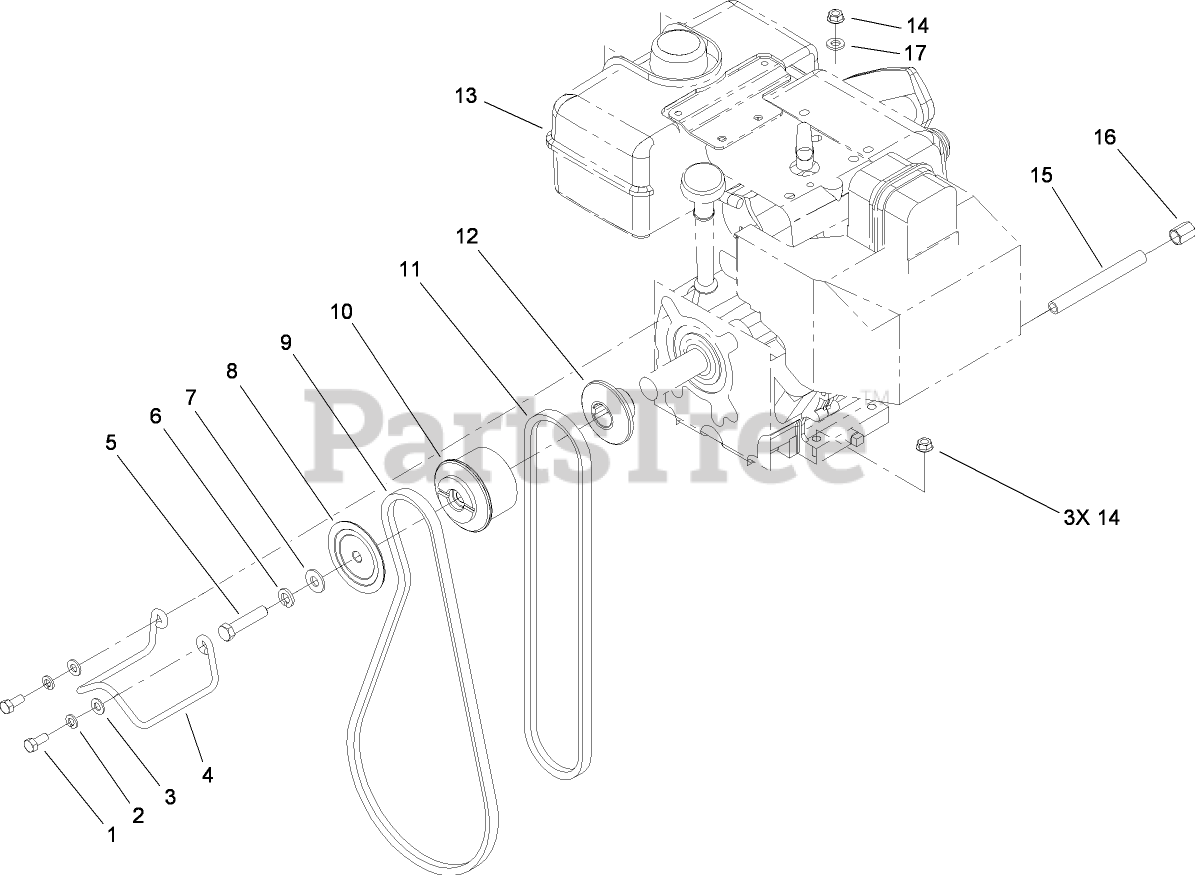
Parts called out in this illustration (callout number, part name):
1	SCREW-HH
2	WASHER-LOCK
3	WASHER-PLAIN
5	SCREW-HH
6	WASHER-LOCK
7	WASHER-FLAT
8	SHEAVE-HALF, IMPELLER
9	BELT-V
10	PULLEY-ENGINE, CENTER
11	V BELT-TRACTION
12	SHEAVE-HALF, TRACTION
13	Loose Parts Package
14	NUT-HF
15	NIPPLE-PIPE
16	CAP-PIPE
17	WASHER-FLAT
